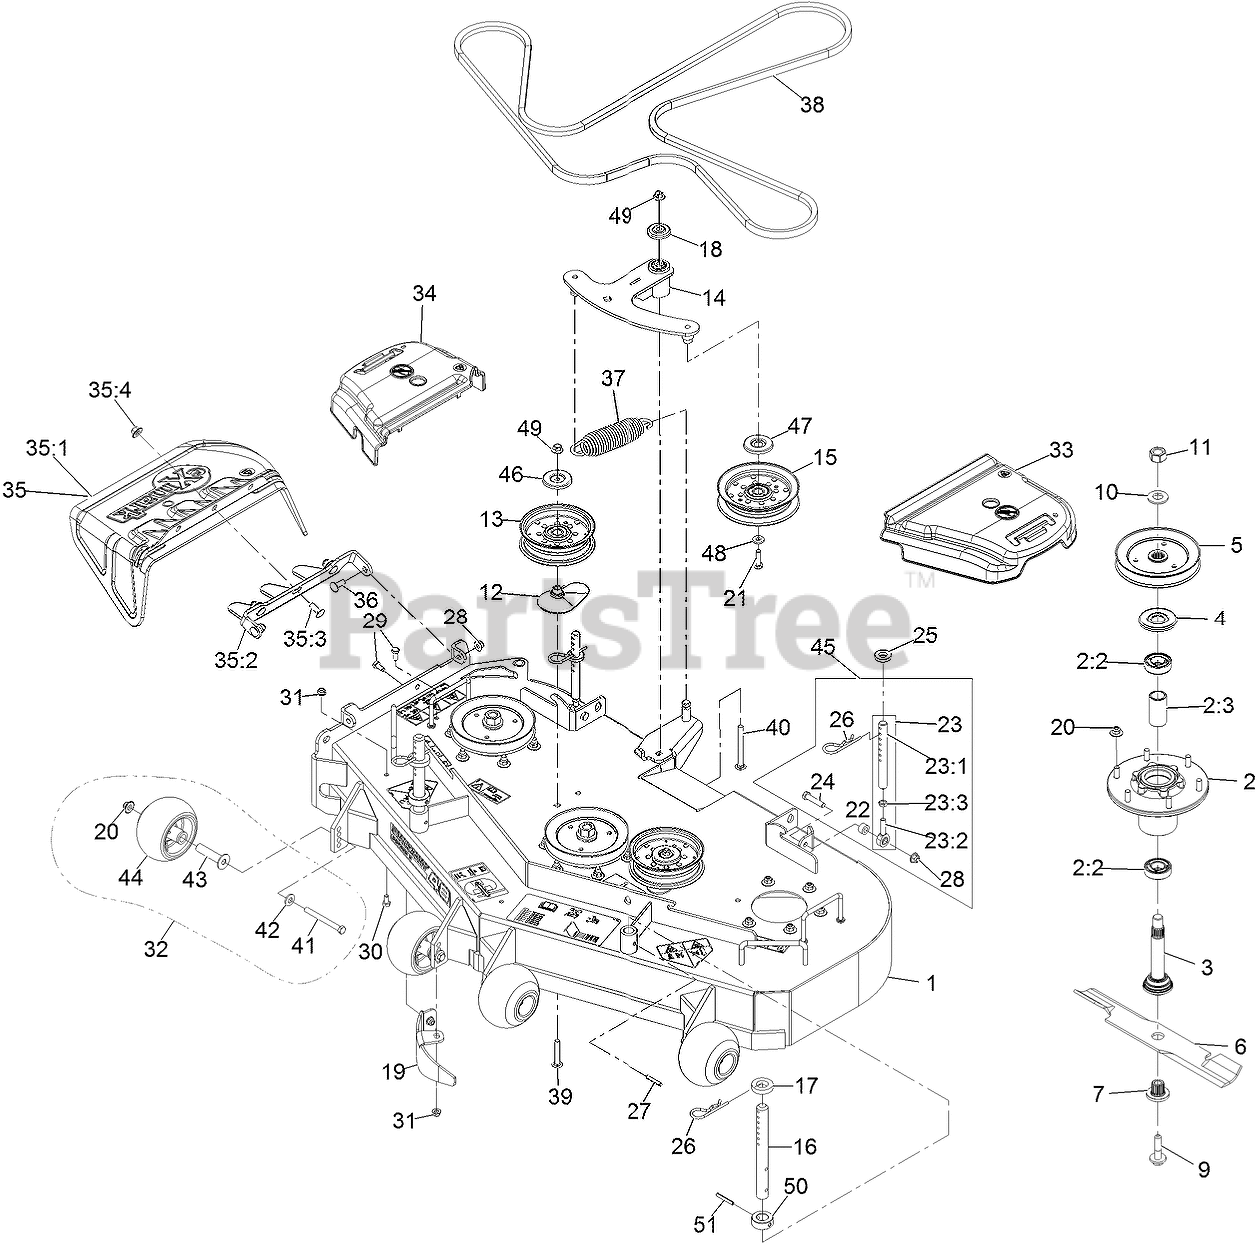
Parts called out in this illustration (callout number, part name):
1	ASM, DECK 48" W/DECALS
2	ASM-CUTTER HSG WITH BEARINGS
2:2	BEARING-BALL
2:3	SPACER-BEARING
3	ASM-SPINDLE AND SEAL
4	GUARD,BEARING TOP .989
5	SHEAVE,BLADE DRIVE 5.90
7	BUSHING,SPLINED
9	SCREW,SEMS 1/2-20 X 2.19
11	NUT-HEX
12	SPACER-PULLEY
13	IDLER-PULLEY, FLAT 5.00X1
14	ASM, DECK IDLER
15	IDLER-PULLEY, FLAT
16	ROD, DECK SUPPORT TTS
17	SPACER-DECK SUPPORT
18	GUARD-TOP
19	BAFFLE, DOGLEG
20	Nut-Nyloc 3/8-16 Flg
21	SCREW-HH
23:1	LINK,SUPPORT
23:2	BALLJOINT
23:3	NUT-HJ
24	SCREW-HH
26	PIN,HAIR COTTER
28	NUT-HF, NI
29	SCREW-HH
30	SCREW-HH
31	NUT-HF, NI
32	KIT, ANTI-SCALP ROLLER
33	COVER-BELT, LH
34	COVER-BELT, RH
35	ASM, DISCHARGE CHUTE
35:1	CHUTE,DISCHARGE
35:2	BRACKET, DISCHARGE CHUTE
35:3	SCREW-CARR
35:4	Nut-Nyloc 3/8-16 Flg
36	SCREW-CARR
37	SPRING-EXTENSION
39	BOLT-CARR, SHORT NECK
40	SCREW-CARR
41	SCREW-HH 3/8-16 X 3 3/4 GR 8
42	WASHER-BELLEVILLE
43	AXLE, ROLLER
44	ROLLER-SCALP, ANTI
45	KIT,SUPPORT LINK W/PIN
46	SHIELD-DUST
47	SHIELD-GUARD, DUST
50	COLLAR, DECK HEIGHT PIN
51	PIN-ROLL
